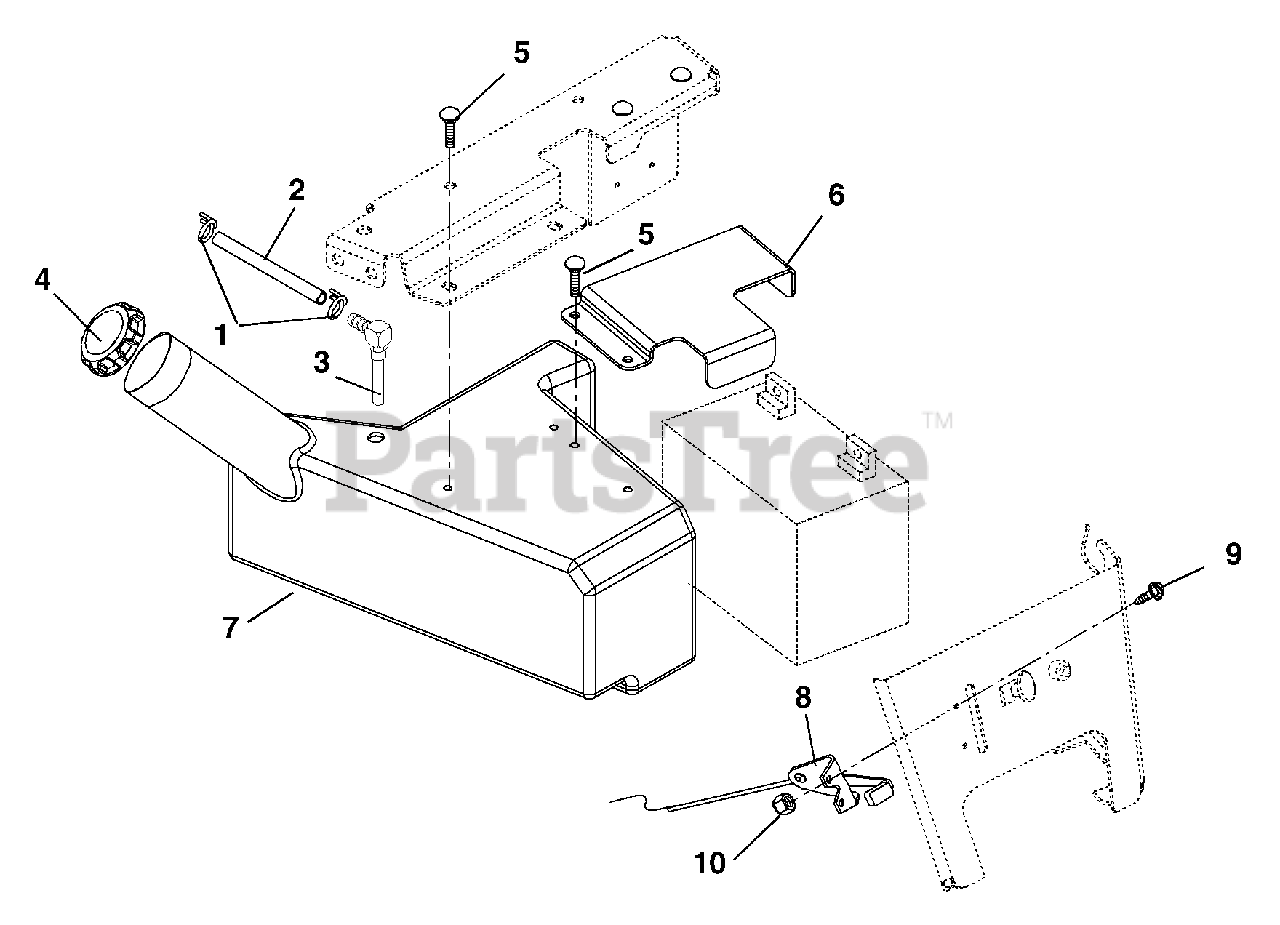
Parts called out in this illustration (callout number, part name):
1	Clamp, Hose Wire .490/.510 x .116
2	Gas Line, Bulk 1/4" I.D.
3	Fitting, Tank
4	Fuel Cap
5	Bolt, Hex .25-20 x .75 Grade 5
6	Bracket, Battery
7	Tank, Fuel
8	Cable, Throttle 19.5
9	Screw, Machine 10-24 x .50 Hex Washer Head
10	Nut, Locking Nylon 10-24 with Insertg
